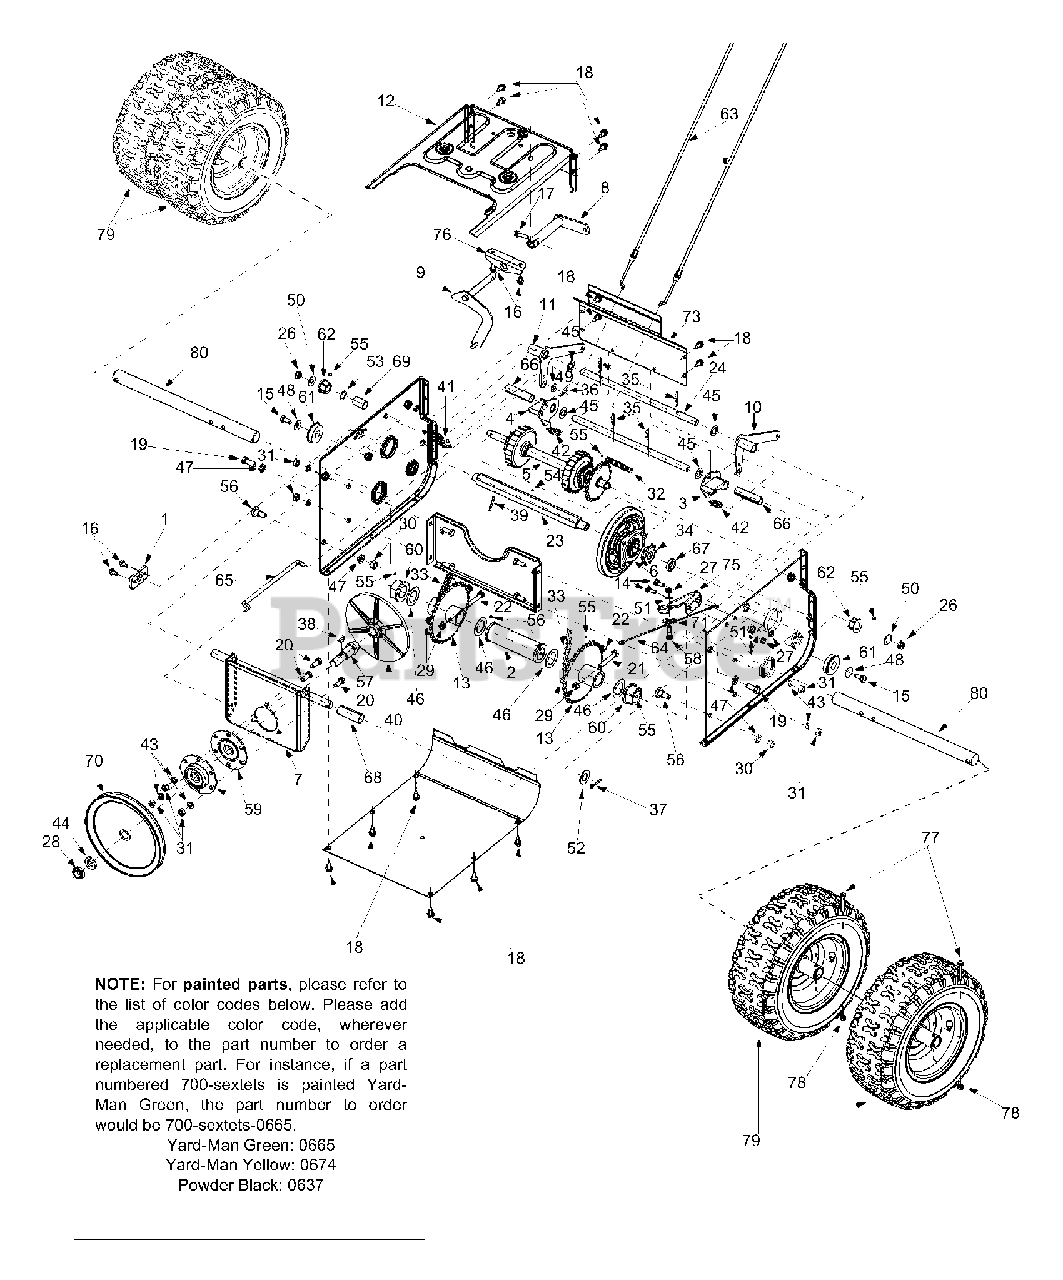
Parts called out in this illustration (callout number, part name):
1	Support Bracket: Pivot
2	Bush Assembly
3	Dogg Assembly LH
4	Dogg Assembly RH
5	Shift Assembly
6	Wheel Bearing Assembly
10	Auger Actuator Bracket Assy.
14	Hex Screw1/4-28 x .625"
15	Hex Screw5/16-18 x .625"
16	TT Screw 1/4-20 x .5"
17	TT Screw 1/4-20 x 1"
18	TT Screw1/4-20 x .625"
19	Hex Screw 3/8-16 x .880"
20	Hex Screw 5/16-18 x .75"
21	Hex Screw 5/16-18 x 2"
22	Hex Screw 5/16-18 x 1.75"
23	Hex Shaft: Drive
24	Actuator Shaft
26	Lock Nut
27	Hex Nut 1/4-28
28	Jam Lock Nut
29	Hex Lock Nut
30	Hex Nut 3/8-16
31	Hex Nut 5/16-18
32	Chain
33	Chain
34	Sprocket
35	Hairpin Clip
36	Hairpin Clip
37	Cotter Pin
38	Key
39	Roll Pin
40	Drive Plate
41	Extension Spring
42	Extension Spring
43	Lock Washer 5/16
44	Lock Washer 5/8
45	Flat Washer
46	Flat Washer
47	Lock Washer
48	Beleville Washer
49	Flat Washer
50	Flat Washer
51	Lock Washer
52	Flat Washer
53	Flat Washer
54	Lubricant
55	Grease
56	Shoulder Screw
57	Spindle: Drive Plate
58	Shoulder Screw 1/4-28 x .375"
59	Bearing Housing Assembly
60	Flange Bearing
61	Ball Bearing
62	Hex Flange Bearing
63	Steer Cable
64	Idler Cable: Auger
65	Clutch Rod: Drive
66	Split Spacer
67	Spacer
68	Split Spacer
69	Spacer
70	Drive Pulley
71	Roller Cable
77	Hex Screw 5/16-18 x 2"
78	Lock Nut
80	Axle: Wheel
